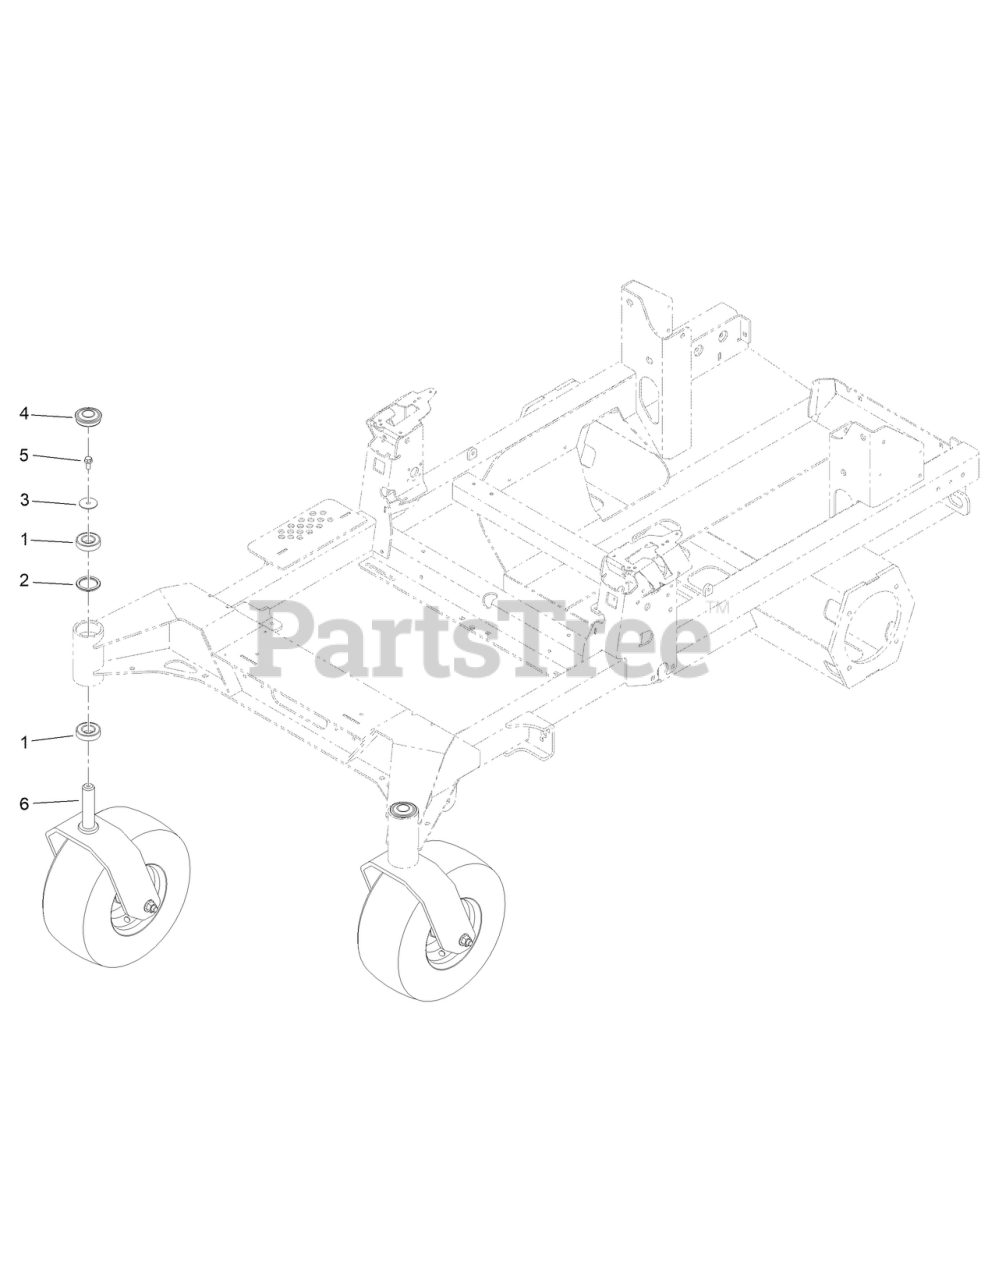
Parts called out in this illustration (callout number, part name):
1	BEARING-BALL
2	SPACER-BEARING
3	WASHER-FLAT
4	CAP,GREASE
5	SCREW-HHF
6	FRONT CASTER W/ FORK ASM
